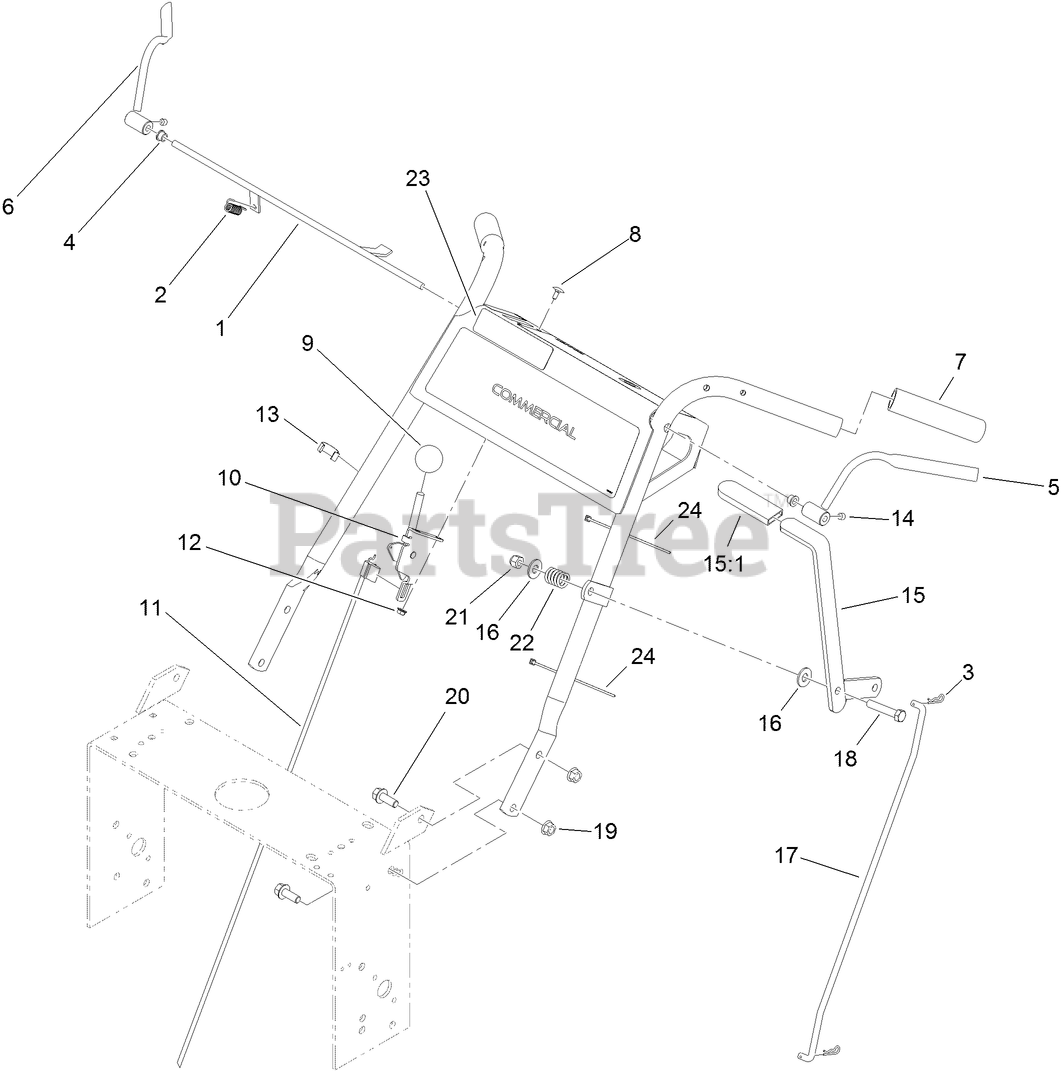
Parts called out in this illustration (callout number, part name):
1	ROD-CONTROL, OPERATOR PRESENCE
2	SPRING-EXTENSION
3	PIN-COTTER
4	BUSHING-NYLON
5	LH OPERATOR PRESENCE CONTROL LEVER ASM
6	RH OPERATOR PRESENCE CONTROL LEVER ASM
7	GRIP-FOAM
8	BOLT-CARR
9	KNOB-BALL
10	LEVER-CONTROL
11	CABLE-CONTROL, THROTTLE
12	NUT-LOCK, FLANGE
13	Clip-Cable
14	SCREW-SET
15	LEVER ASM
15:1	GRIP-LEVER
16	WASHER-FLAT
17	Linkage-Blade, Upper
18	SCREW-HH
19	NUT-HF
20	SCREW-HHF
21	NUT-LOCK, NI
22	SPRING-COMPRESSION
23	DECAL-ARRESTER, SPARK
24	TIE-CABLE
